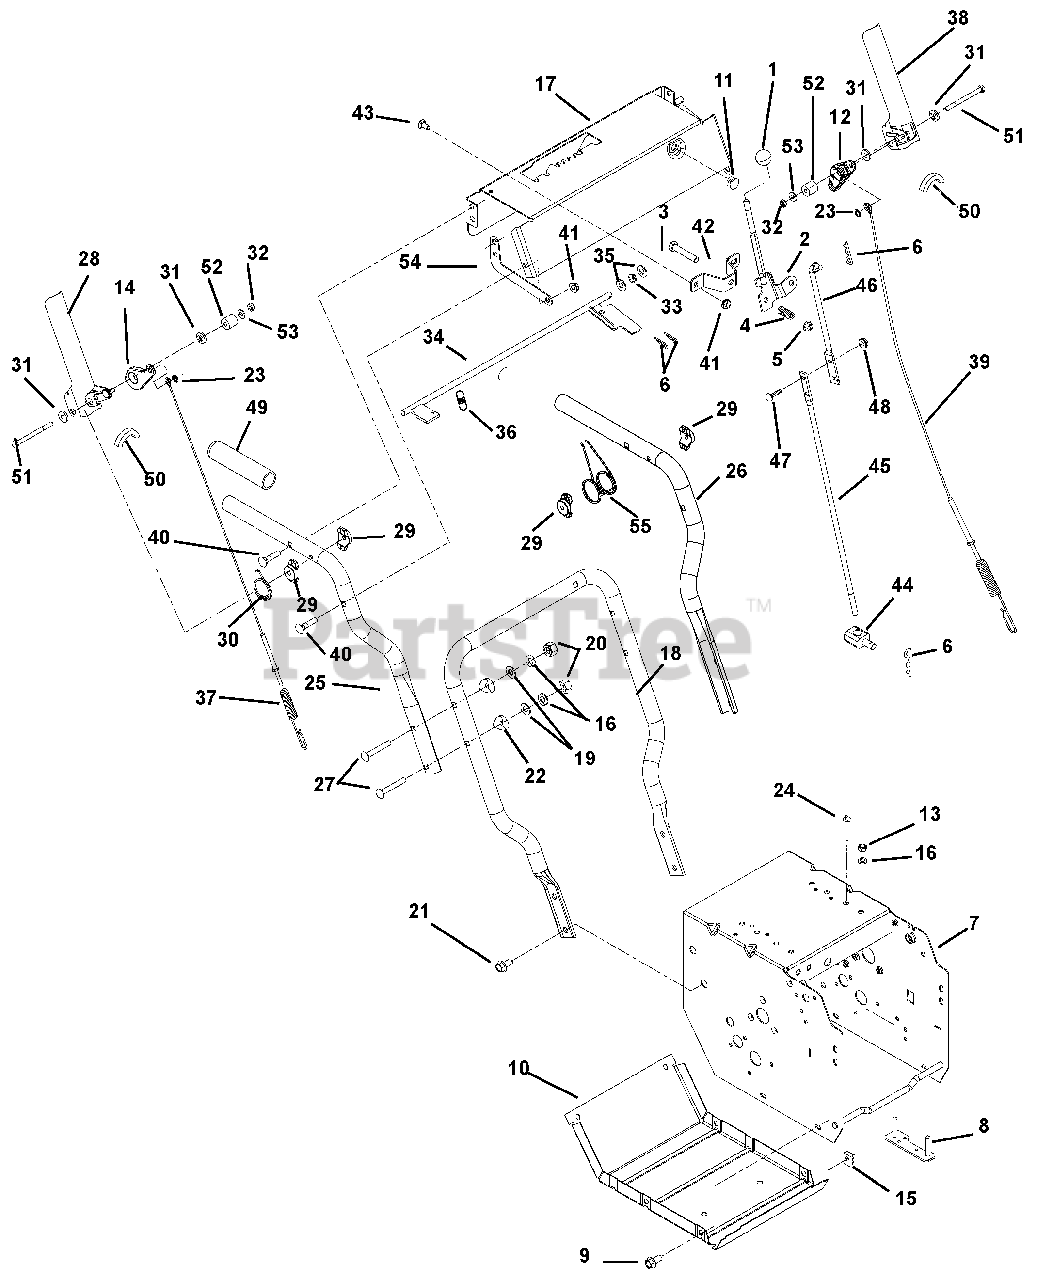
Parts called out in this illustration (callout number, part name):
1	KNOB,BALL -BLACK 1.47" .375-16
2	WMT, SHIFT LEVER
3	@BLT-HEX .38-16X2.00 GR5 YWZC
4	SG-COMP .125X.781X1.250
5	@NUT-LK-TOP-FLG .38-16 YWZC
6	PIN-HAIR INT .08X.18X1.18 YWZC
7	FRAME, 920/921
8	STRAP, ENGINE BOLT-WELDMENT
9	BLT-HEX .25-20X.75 HWH YZ GR5
10	COVER, BOTTOM
11	HOLE PLUG, PLASTIC .44 HOLE
12	CAM, INTERLOCK - LH
13	@NUT-HEX .31-18 YWZC
14	CAM, INTERLOCK - RH
15	NUT-RTNR .25-20X.56
16	WSHR-LK .312X.097 HVY YWZC
17	DASH, SNO TEK (W/DECALS)
18	HANDLEBAR, LOWER (COMPACT)
19	@WSHR-FL-STL.38X.875X.083 YWZC
20	@NUT-LK-NYL .312-18 YWZC
21	BLT-SERHFWH .38-16X.75 YWZC
22	SPACER, HANDLEBAR
23	RG-RTNG-EXT .250X.010
24	RVT-POP .187 YZ
25	HANDLEBAR, UPPER - RH COMP/DEL
26	HANDLEBAR, UPPER - LH COMP/DEL
27	@BLT-RDHDSQNK .31-18X2.25 G5YZ
28	PADDLE, CLUTCH - RH COMPACT
29	SPACER, HANDLEBAR
30	SPRING, TORSION
31	BSHG, FLG .266X.42X.150 PM
32	NUT-JAM-NYL .250-20 W/INSERTYZ
33	BUSHING, POLYLINER-.38 SNAPIN
34	WELDMENT, INTERLOCK SHAFT
35	@WSHR-FL-STL.406X.812X.065 YWZ
36	SPRING, EXTENSION
37	CABLE, ATTACHMENT, COMPACT
38	PADDLE, CLUTCH - LH COMPACT
39	CABLE, TRACTION - COMPACT
40	BLT-RDHDXLSQNK .31-18X1.5 G5YZ
41	@NUT-LK-TOP-FLG .31-18 YWZC
42	BRKT, SHIFT MOUNT
43	@BLT-RHDSSQNK .31-18X.62 G5YZ
44	PIVOT,SHIFT ROD .375-16(TRUNN)
45	ROD, SHIFT - LOWER
46	ROD, SHIFT - UPPER
47	@BLT-RDHDSQNK .25-20X.75 G5YZ
48	@NUT-LK-TOP-FLG .25-20 YWZC
49	HANDLE GRIP
50	EDGING, CLUTCH PADDLE - 2.00"
51	@BLT-HEX .25-20X3.25 YWZC
52	BSHG, SLV .266 X .750 X .750
53	@WSHR-FL-STL.281X.62X.065 YWZC
54	STRAP, SUPPORT - DASH PANEL
55	SPRING, TORSION, DUAL COIL
